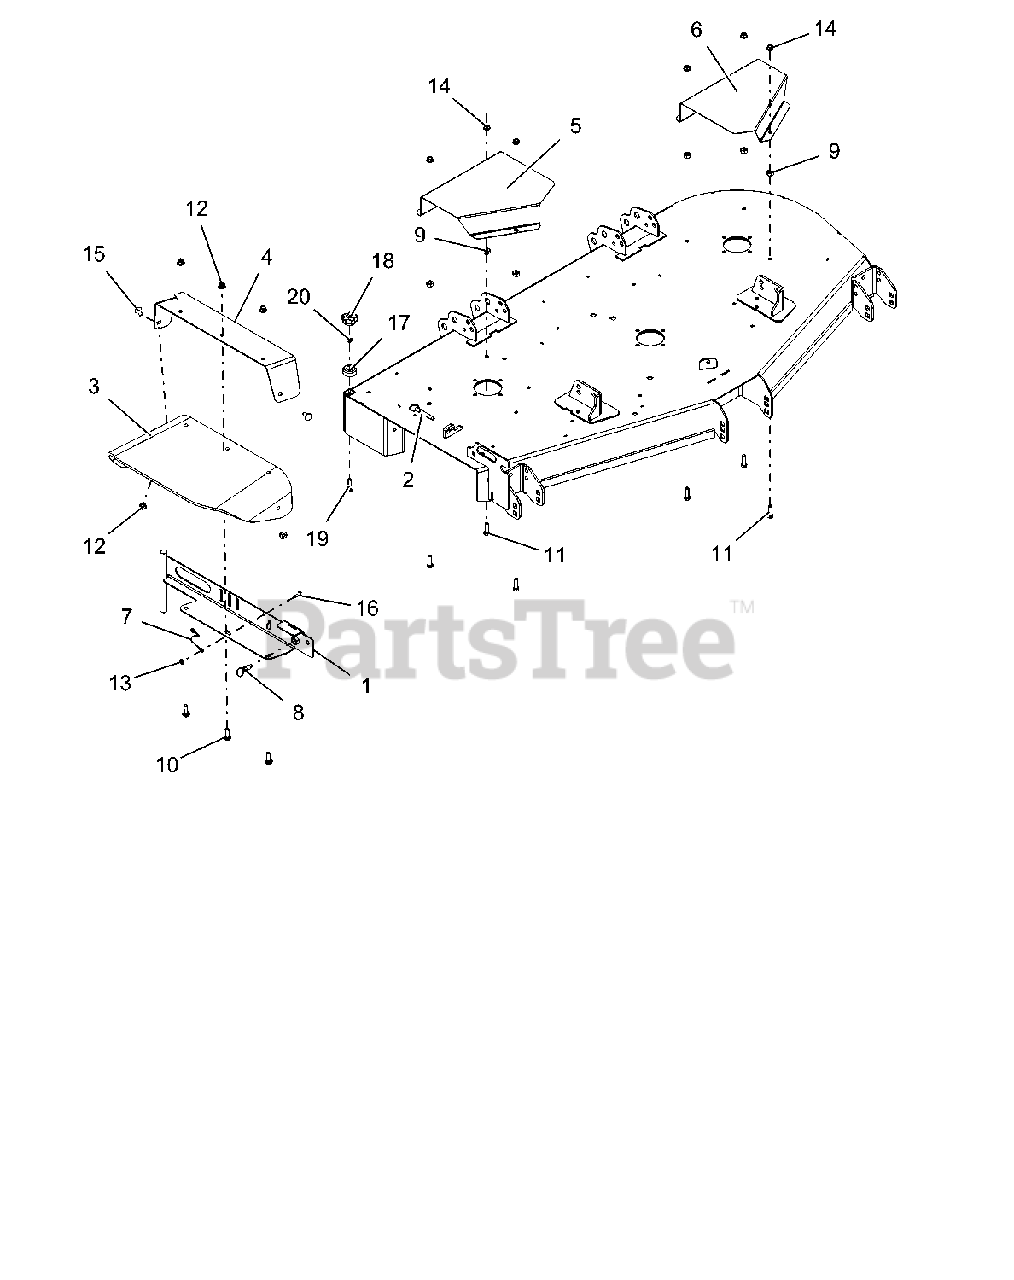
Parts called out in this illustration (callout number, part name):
1	WLDMT, DISCHARGE CHUTE 52"-60"
2	PIN, SPRING BALL .375OD X 1.50
3	CHUTE, RUBBER DISCHARGE
4	CHT SPPRT MTG BRKT W/SAFETY
5	GUARD, DECK 60"-66" RH
6	GUARD, DECK 60"-66" LH
7	CABLE, 6.0 LANYARD, NYLON
8	PULL PIN,.50-13THDX.310 PLNGR
9	NUT-HEAVY HEX .38-16 YWZC
10	@BLT-RDHDSQNK .38-16X1.25 G5YZ
11	@BLT-HEX .38-16X1.25 GR5 YWZC
12	@NUT-LK-NYL-FLG .38-16 YWZC
13	@NUT-LK-TOP-FLG .25-20 YWZC
14	@NUT-SPNLK-FLG .375-16 YWZC
15	@BLT-RDHDSQNK .38-16X1.00 G5YZ
16	@BLT-HEX .25-20X.75 GR5 YWZC
17	BUMPER,RECESSED1.50X.63 W/.31
18	KNOB-CLAMPING, .312-18 NYLOC
19	@BLT-RDHDSQNK .31-18X1.50 G5YZ
20	@NUT-LK-CTR .31-18 YWZC
